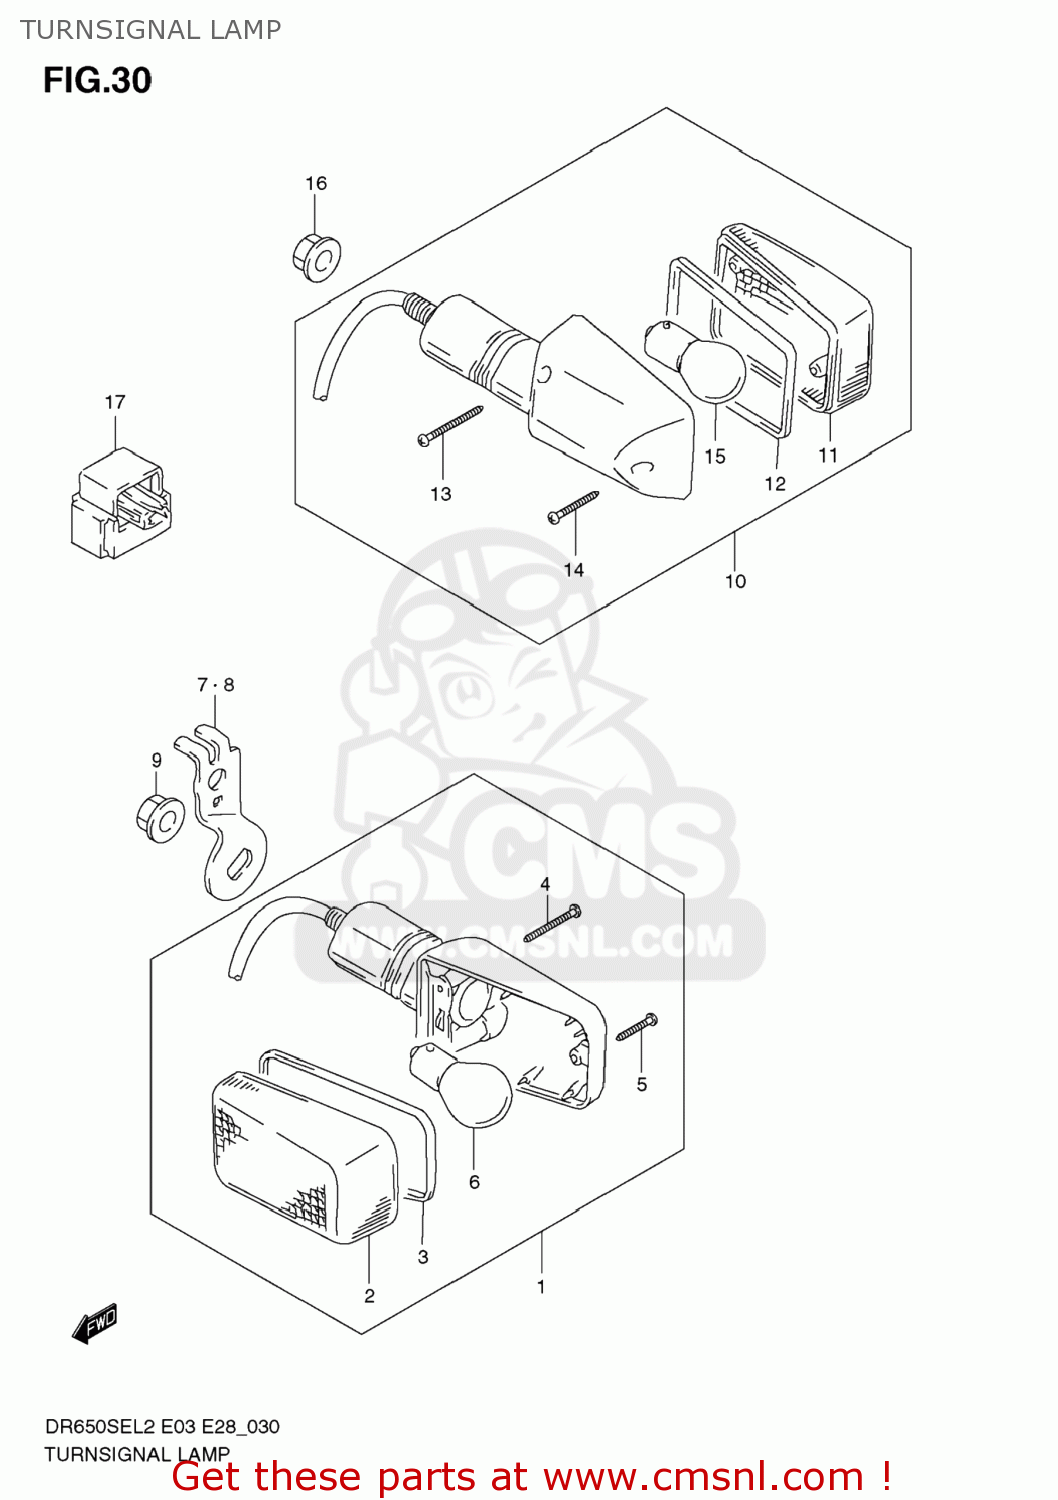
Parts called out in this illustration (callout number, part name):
1	LAMP ASSY,FR TURN SIGNAL
2	LENS
3	GASKET (NAS)
4	SCREW(3X30)
5	SCREW
6	BULB(12V21W)
7	BRACKET,FR TURNSIGNAL,R
8	BRACKET,FR TURNSIGNAL,L
9	NUT
10	LAMP ASSY,RR TURNSIGNAL,R
11	LENS
12	GASKET (NAS)
13	SCREW(3X30)
14	SCREW
15	BULB(12V21W)
16	NUT
17	RELAY ASSY
